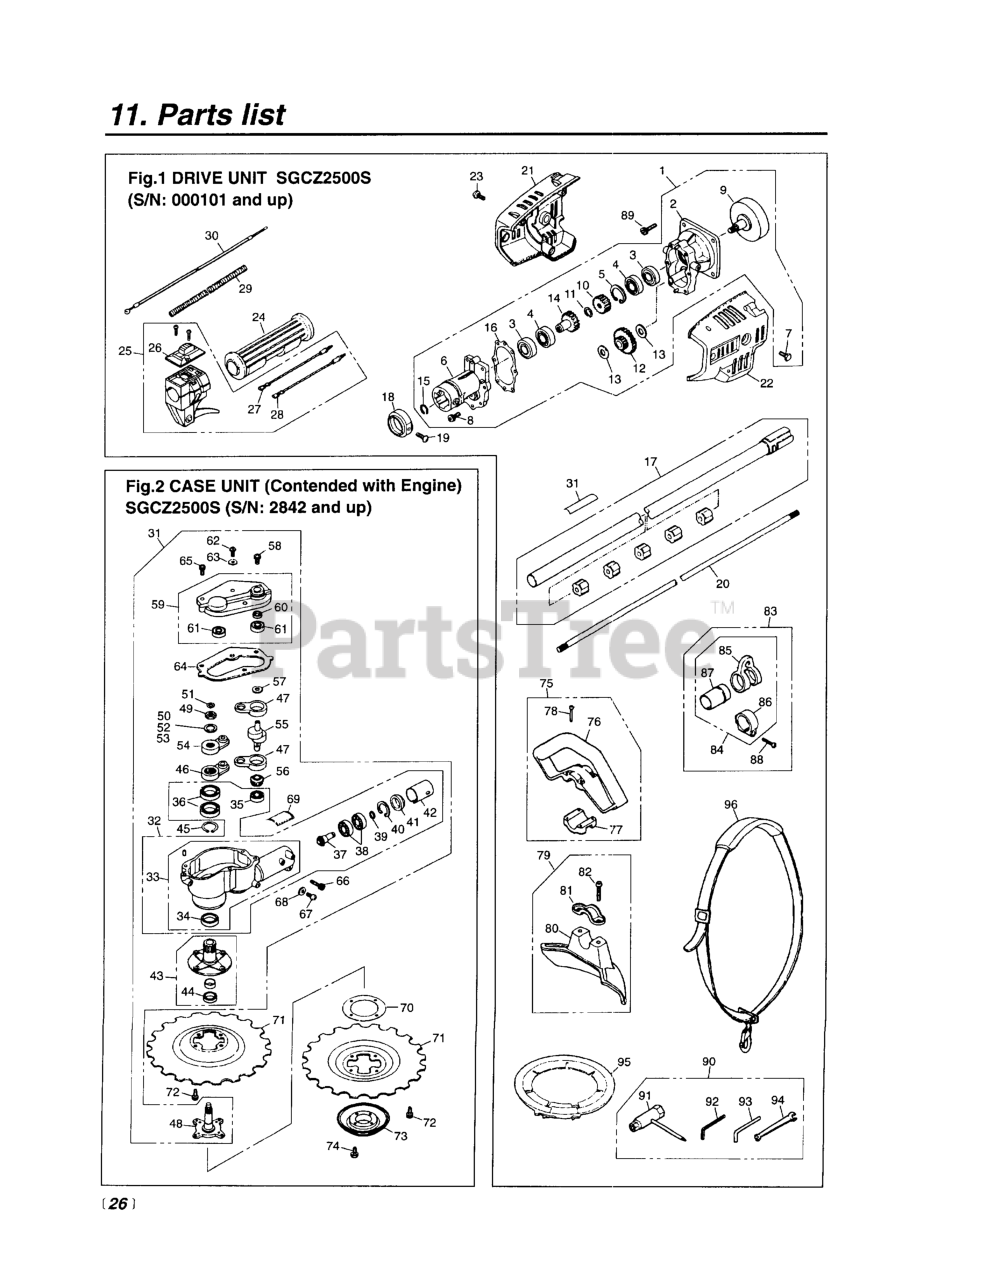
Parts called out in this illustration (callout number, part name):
1	MISSION ASSEMBLY
1-31	PLATE, NAME
2	CASE, REAR COMP (RPLS -11101)
2-31	CUTTERCASE ASSEMBLY
4	BEARING
5	RING, SNAP, M28 x 1.2
6	CASE, FRONT
7	BOLT, M6 x 8
8	BOLT, M5 X 20
9	DRUM
10	GEAR, PINION
11	RING, SNAP
12	GEAR (RPLS 3805-11330)
13	WASHER
14	GEAR, WHEEL
16	GASKET (RPLS 3805-11411)
17	PIPE COMP (RPLS 3805-12100)
18	CAP
19	SCREW, M5 X 10
20	SHAFT
21	COVER, RIGHT (RPLS. -11510)
22	COVER, LEFT (RPLS -11520)
24	GRIP (RPLS 3577-32140 & 3220-
25	LEVER COMP (RPLS. T3065-12200)
27	CORD (A), BLACK
28	CORD (B), RED
29	TUBE (RPLS 4900-72141)
30	CABLE COMP
32	CUTTERCASE (RPLS -98100)
34	SEAL, OIL
36	BEARING
37	PINION
38	BEARING (RPLS T3403-13510)
39	RING, SNAP
40	RING, SNAP, M26 X 1.2
41	PACKING
42	SPACER (RPLS -13950)
43	SHAFT, OUTER-C
44	SEAL, OIL
45	RING, SNAP, M20 x 1.2
46	ARM, LOWER (RPLS -13411)
48	SHAFT, INNER
50	SHIM, 0.3t
52	SHIM, 0.2T
53	SHIM, 0.1t
54	ARM, UPPER (RPLS -13611)
55	CRANKSHAFT (RPLS -13710)
56	GEAR
57	WASHER, M8 x 1.2
58	BOLT
59	COVER COMP
60	SEAL, OIL
62	SCREW, M6 x 10
63	WASHER, M6 x .8
64	GASKET
65	BOLT, M5 x 20
66	BOLT, M6 x 1.35
67	SCREW, M5 x 14
68	WASHER, M5x.8(RPLS 01624-20508
69	LABEL, CAUTION
72	BOLT, M6 x 8
73	STABILIZER (RPLS -15151)
74	SCREW, M5 X 8
75	HANDLE ASSEMBLY
76	HANDLE
78	SCREW, M5 x 35
79	GUARD ASSY (RPLS -24000)
80	GUARD (RPLS -24110)
81	CLAMP (REPLACES 5807-24120)
82	BOLT, M6 x 1.30
83	HANGER ASSEMBLY
84	HANGER COMPLETE
85	HANGER
86	CLAMP
87	SLEEVE
88	SCREW, M5 x 25
89	BOLT, M6 x 20
90	TOOL SET (SGCZ2500S)
91	SOCKET
92	WRENCH (TOOL)
93	WRENCH (TOOL)
94	SPANNER, 8 X 10 (RPLS 2540- )
95	COVER (REPLACES D0041) ACC.
